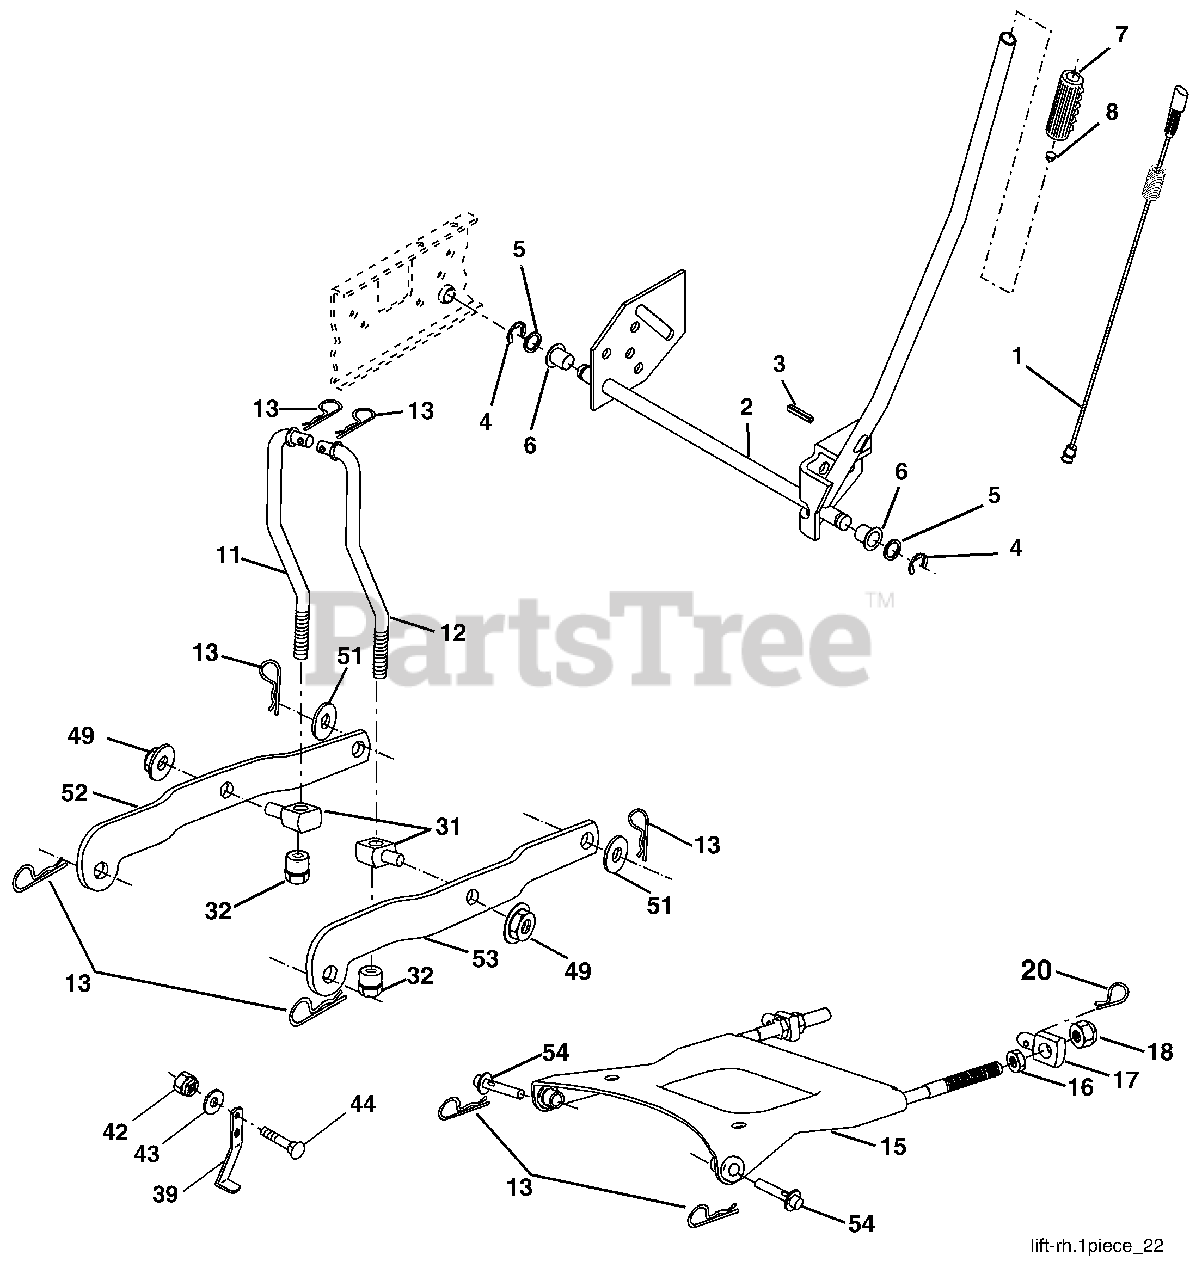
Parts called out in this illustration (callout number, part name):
1	Wire Asm Inner/Sprg W/plunger
2	Shaft Asm Lift RH w/Inf
3	Pin Groove
4	E Ring #5133-62
5	Washer 21/32 X 1 X 21 Ga
6	Bearing Nylon Blk 629 Id
7	Grip Handle
8	Button Plunger
11	Link Lift LH
12	Link Lift RH
13	Retainer Spring
15	Plate Asm Suspension
16	Nut Hex Jam 1/2-13 unc
17	Trunnion
18	Locknut Hex W/Washer Insert 1/2-13
20	Retainer Spring
31	Trunnion
32	Nut Lift Link
39	Upstop
42	Nut 3/8-16
43	Washer 13/32 x 1 x 12 Ga.
44	Bolt 3/8-16 x 1
49	Nut Hex Flange Lock
51	Washer 17/32 x 7/8 x 13 Ga.
52	Arm Suspension Rear LH
53	Arm Suspension Rear RH
54	Pin Flange
